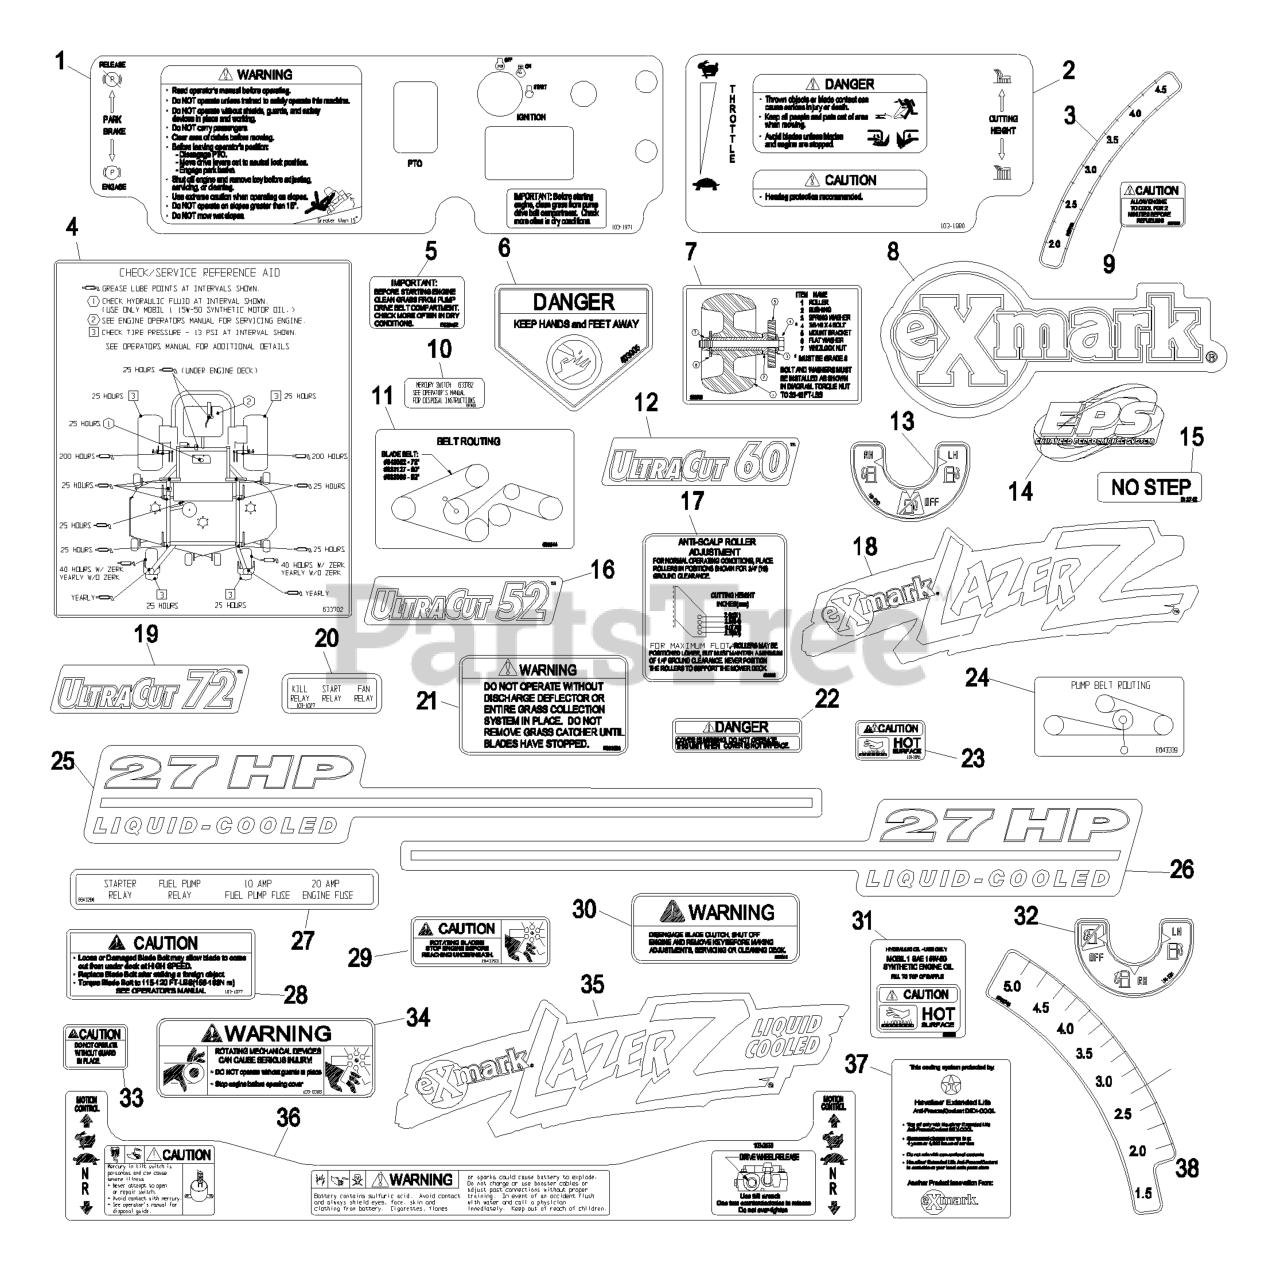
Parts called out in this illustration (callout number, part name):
3	DECAL-HEIGHT, DECK
4	DECAL,CHECK/SERVICE
5	DECAL-IMPORTANT
6	DECAL-DANGER
7	DECAL,ROLLER MOUNTING
10	DECAL-SWITCH, MERCURY
11	DECAL,BELT ROUTING
12	DECAL,ULTRACUT 60
13	DECAL-VALVE, FUEL
15	DECAL,NO STEP
16	DECAL,ULTRACUT 52
17	DECAL,ANTISCALP
19	DECAL,ULTRACUT 72
20	DECAL-RELAY
21	DECAL-WARNING, DISCHARGE
22	DECAL-COVER, MISSING
23	DECAL-CAUTION
24	DECAL-ROUTING, BELT
25	DECAL,HOOD 27LC LH
27	DECAL-FUSE/RELAY
28	DECAL,BOLT TORQUE
29	DECAL-FAN, RADIATOR
30	DECAL,WARNING
32	DECAL-VALVE, FUEL
33	DECAL-GUARD
37	DECAL,SHELL COOLANT
38	DECAL-HEIGHT, DECK
